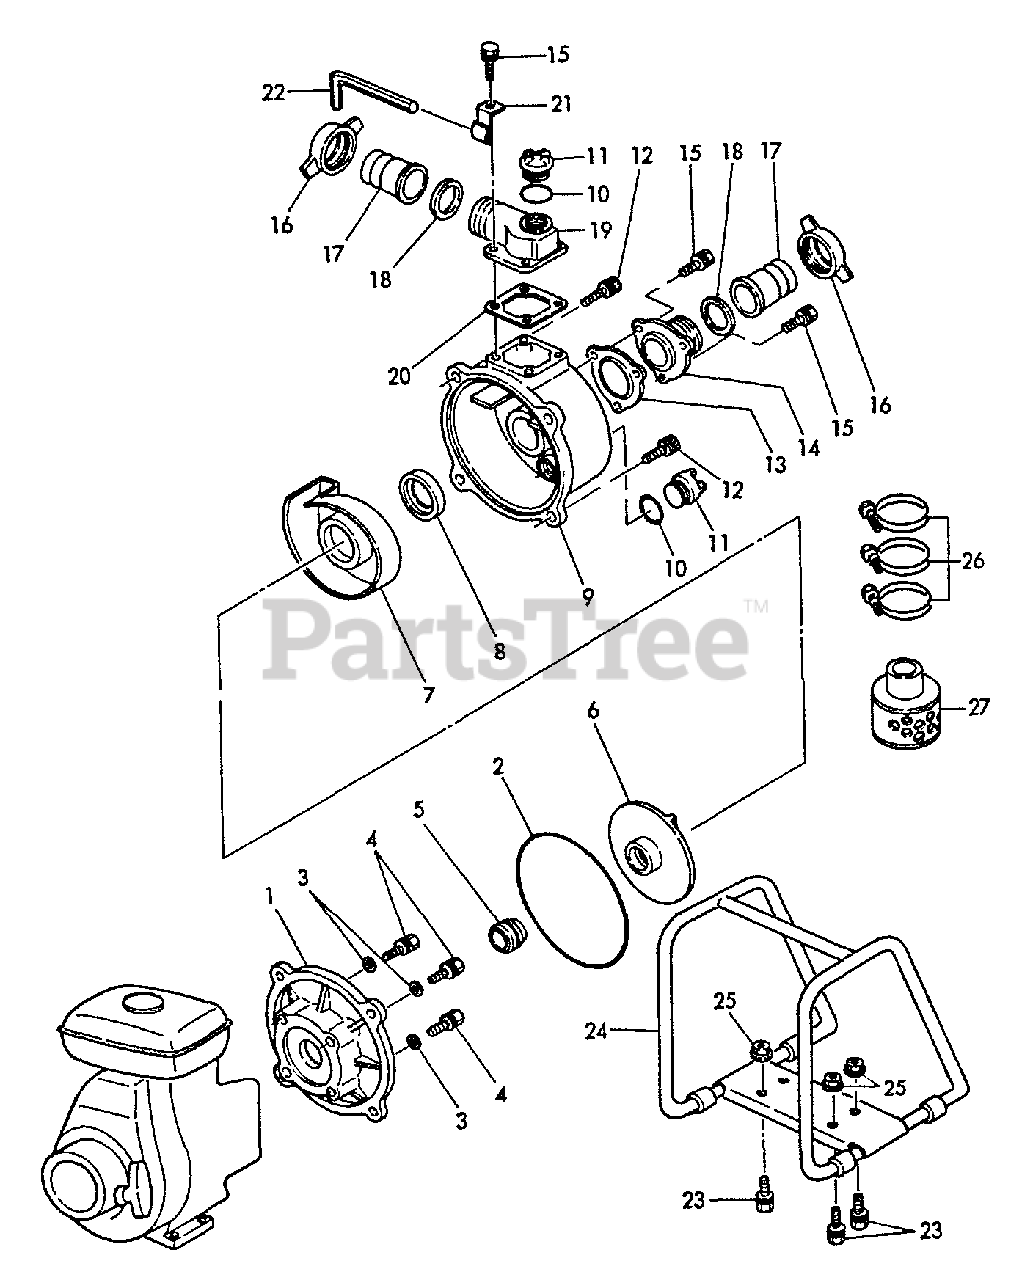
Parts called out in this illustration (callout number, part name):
1	COVER, PUMP CASE
2	GASKET, CASING
3	GASKET, SEAL
4	BOLT - 8X48
5	SEAL
6	IMPELLER
7	CASING, INNER
8	GASKET, INNER CASING
9	CASING
11	PLUG, PRIMING
12	BOLT
13	VALVE, CHECK
14	CASE (NPT), VALVE
15	BOLT - 8X25
16	JOINT, HOSE
17	COUPLING, HOSE
18	GASKET, COUPLING
19	BEND (NPT), DELIVERY
20	GASKET, BEND
21	HOOK
22	HEX KEY
23	BOLT
24	FRAME
25	NUT - FLANGE
26	BAND, HOSE
27	STRAINER, DEBRIS
